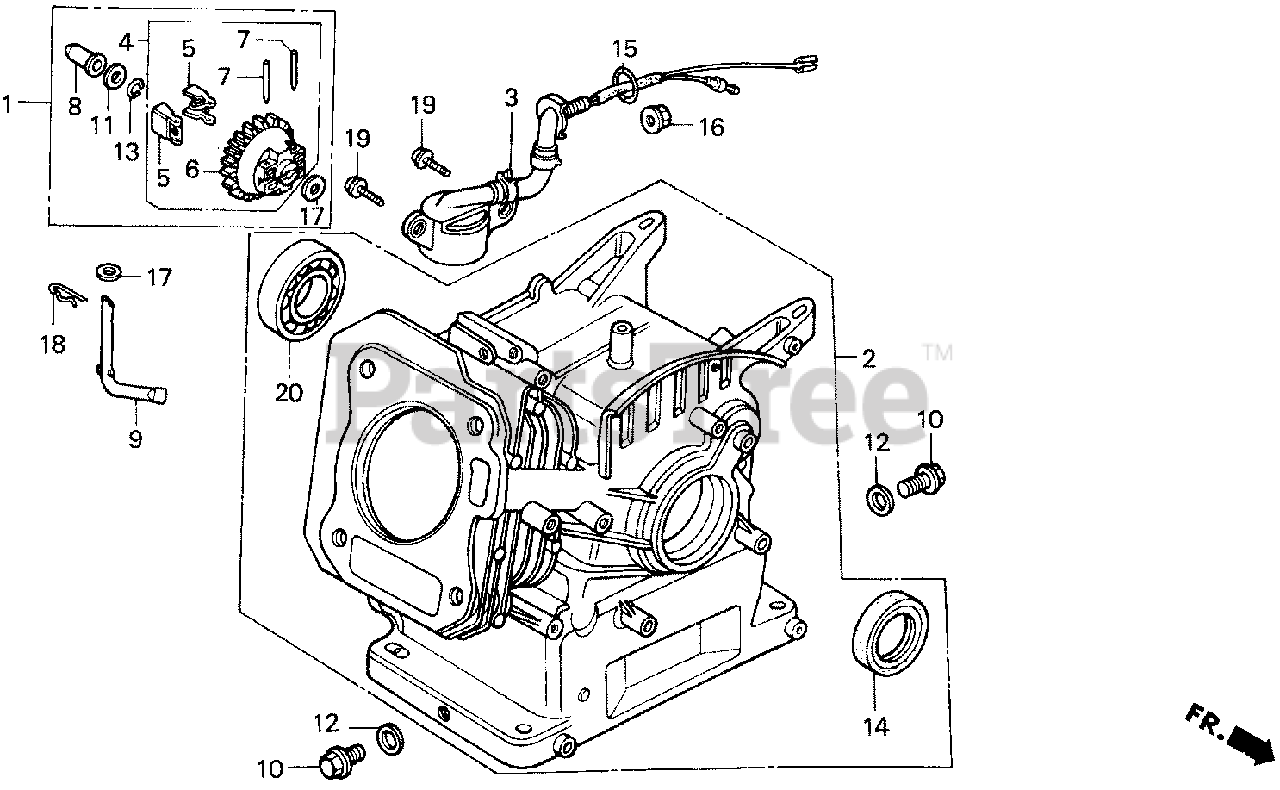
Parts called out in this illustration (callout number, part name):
1	GOVERNOR KIT
2	CYLINDER ASSY. (OIL ALERT)
3	SWITCH ASSY., OIL LEVEL
4	GOVERNOR ASSY.
5	WEIGHT, GOVERNOR
6	HOLDER, GOVERNOR WEIGHT
7	PIN, GOVERNOR WEIGHT
8	SLIDER, GOVERNOR
9	SHAFT, GOVERNOR ARM
10	BOLT, DRAIN PLUG
11	WASHER, THRUST (6MM)
12	WASHER, DRAIN PLUG (10.2MM)
13	CLIP, GOVERNOR HOLDER
14	OIL SEAL (25X41X6)
15	O-RING (13.5X1.5) (ARAI)
16	NUT, FLANGE (10MM)
17	WASHER, PLAIN (6MM)
18	PIN, LOCK (8MM)
19	BOLT, FLANGE (6X12)
20	BEARING, RADIAL BALL (6205)
